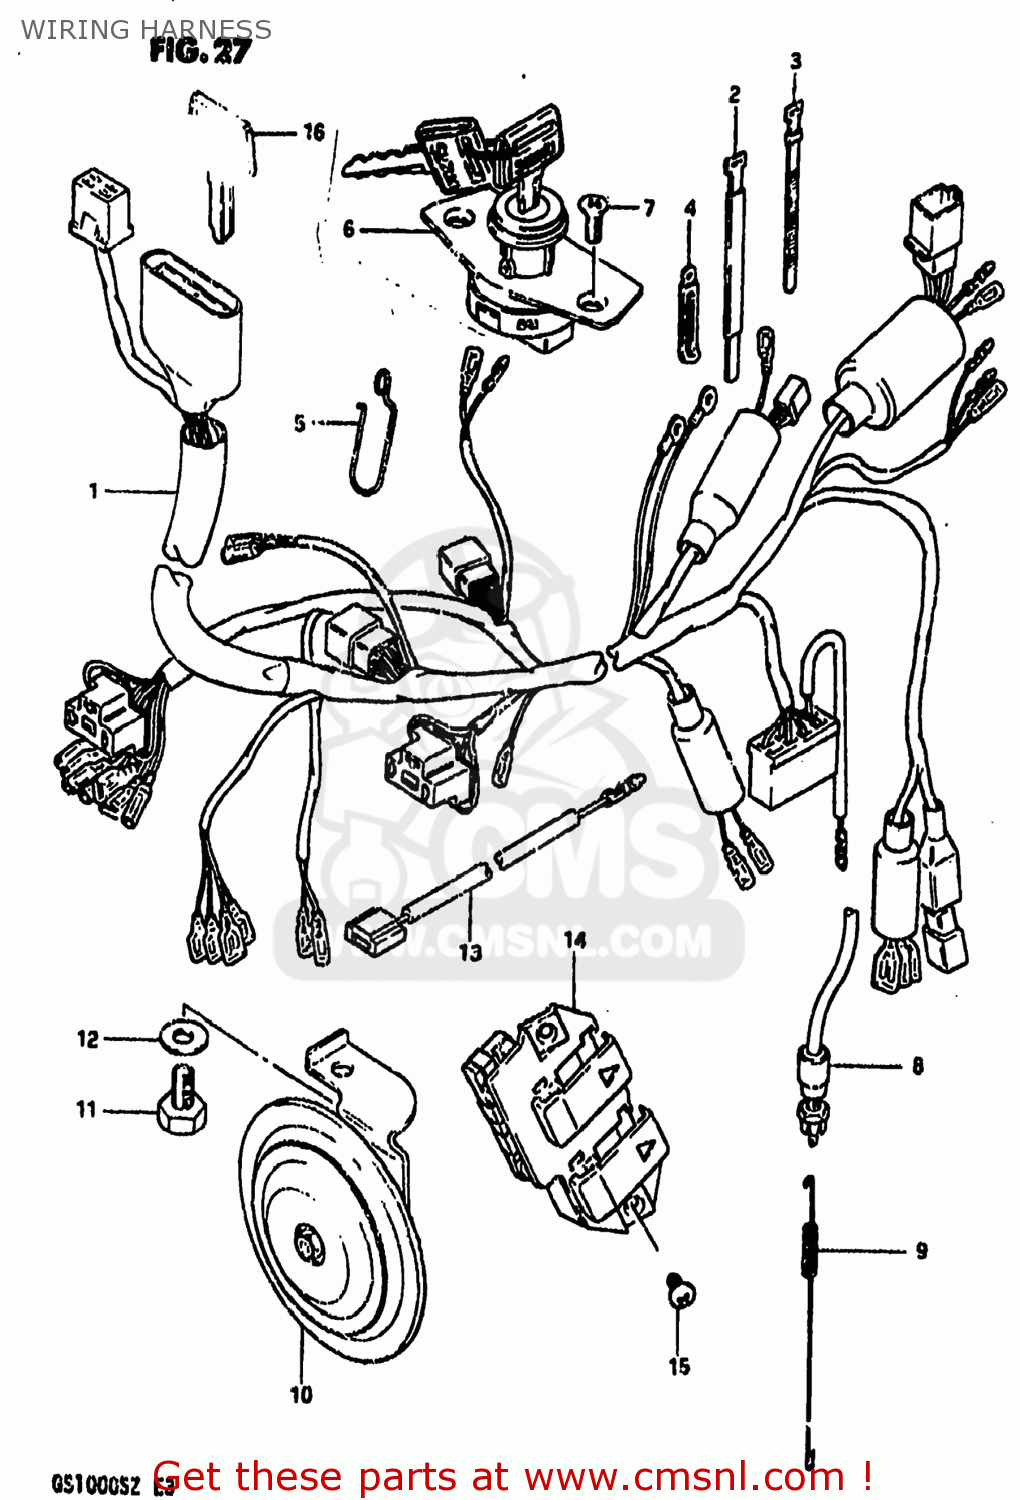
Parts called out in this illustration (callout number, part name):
1	WIRING HARNESS
2	CLAMP
3	CLAMP(L:80)
4	CLAMP
5	BOOT,WIRING HARNESS
6	SWITCH ASSY,IGNITION
7	SCREW
8	SWITCH ASSEMBLY,STOP LAMP
9	SPRING
10	HORN ASSY
11	BOLT 8X12
12	WASHER
13	WIRE
14	SWITCH ASSY,SIDE COVER,L
15	SCREW
16	KEY,BLANK
